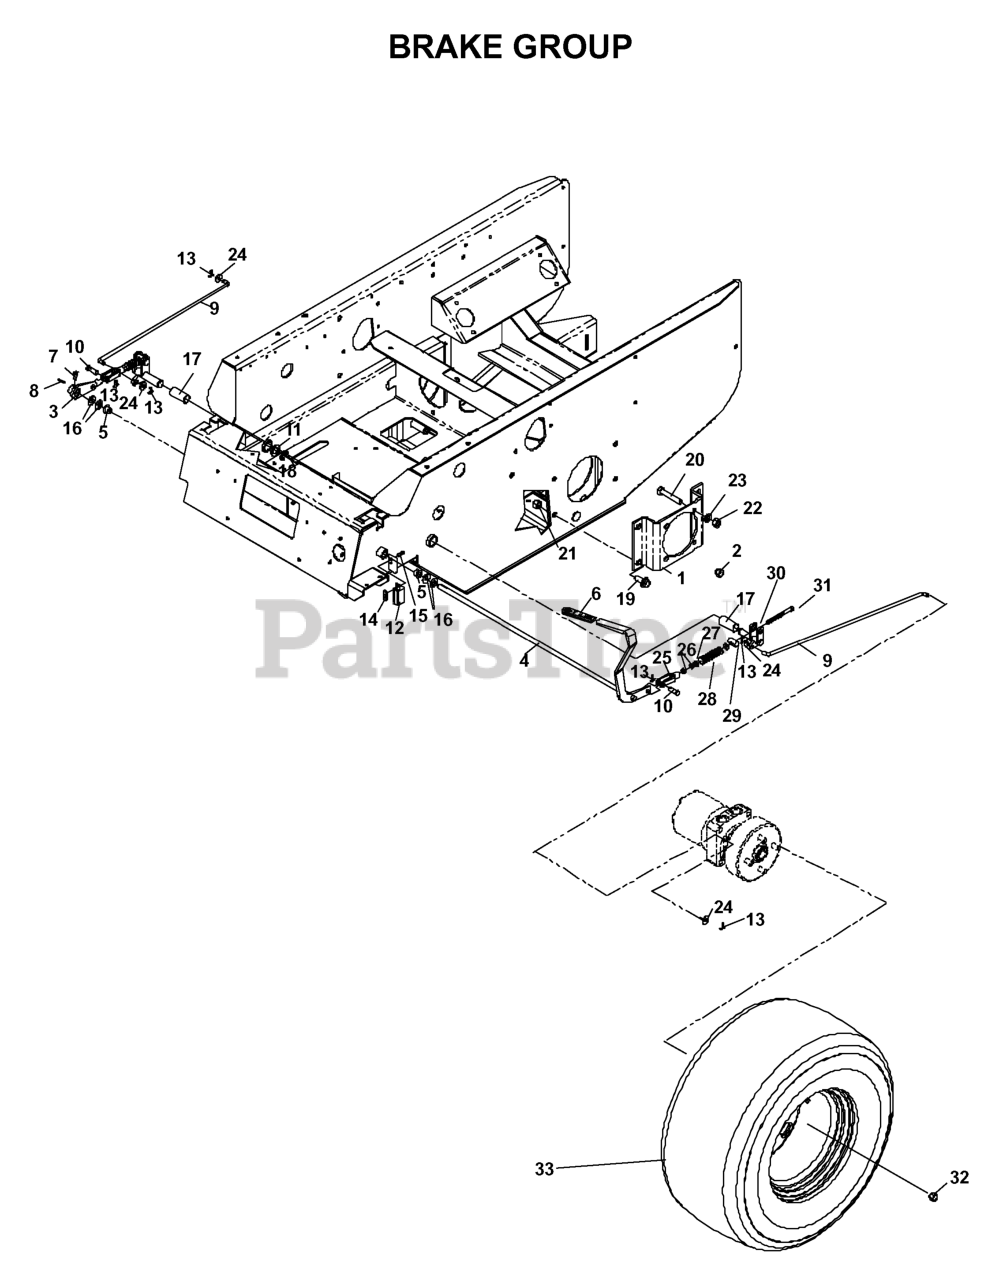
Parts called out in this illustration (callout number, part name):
1	MOTOR STANDOFF - PAINTED
2	LUG NUT 1/2F
3	BRAKE ARM WELDMENT
6	GRIP, PARK BRAKE
7	SCREW 5/16C X 5/8 SQ HEAD
9	BRAKE LINKAGE BAR
10	CLEVIS PIN 3/8 X 1 1/8
13	RP_COTTER PIN 1/8 X 3/4
14	TAPPED PLATE
15	SCREW #10-24 X 5/8
16	WASHER, 7/16 DISC SPRING
17	BRONZE BEARING
18	E RING 3/4
19	HCS 1/2C X 1 1/4 SERRATED HEAD
20	HCS 1/2C X 2 3/4
21	NUT 1/2-13 HEX NYLOC ZD
22	NUT HEX 1/2
23	WASHER 1/2" SPLIT LOCK
24	WASHER 5/16 FLAT
25	YOKE-3/8-24 PLTD
27	WASHER 3/8 SAE FLAT
29	TRUNION PIN
31	HCS 3/8F X SPECIAL
32	LUG NUT 1/2F
33	TIRE/WHEEL ASSY 26 X 12-12
539105487	12"RIM 2.5" NEG OFFSET 8.5" W
539107715	TIRE, 26-12 X 12
539912234	VALVE STEM TR-412
539976856	TIE, PLASTIC
